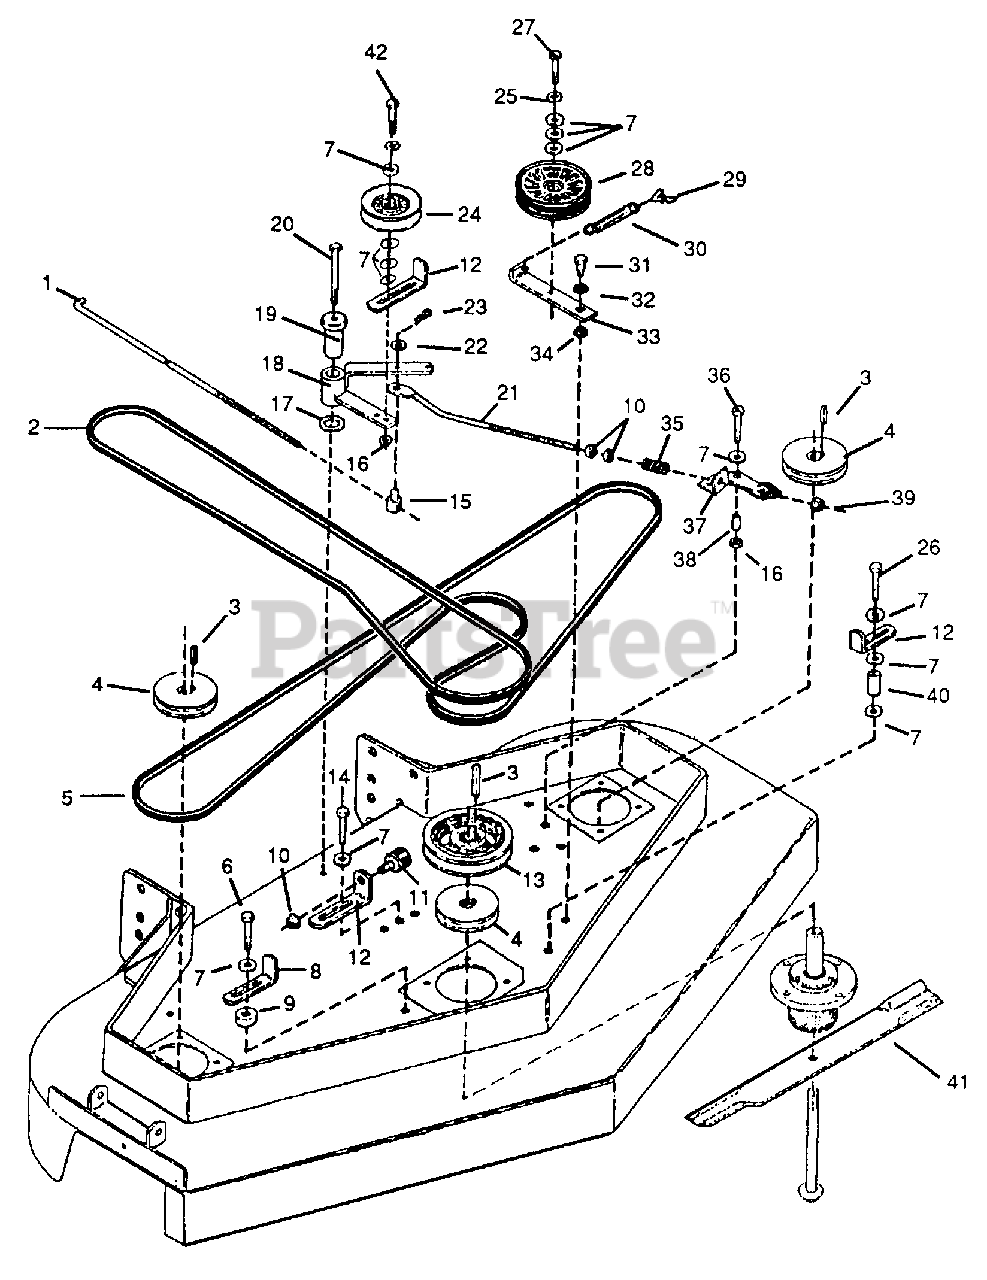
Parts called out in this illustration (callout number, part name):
1	Rod, Blade Engagement
2	Belt, Engine - Blade, 48"
4	Pulley
5	Belt, Blade- Blade, 48"
6	3/8"-16 x 1-1/4' Hex. Hd. Cap Screw
7	3/8" Flat Washer
8	Belt guide
9	Spacer
10	5/16"-18 Flange Nut
11	Bumper, Blade Control Lever
12	Beltguide
13	Pulley
14	3/8" -16 x 1' Hex. Hd. Cap Screw
15	Swivel
16	3/8' Flange Nut
17	1" Machinery Bushing
18	Idler Arm
19	Pivot Bushing
20	3/8' -16 x 3' Hex. Hd. Cap Screw
21	Rod, Blade Brake
22	5/16- Flat Washer
23	#13 Hair Pin Cotter
24	Pulley
25	3/8' Spring Lock Washer
26	3/8 -16 x 2-1/4' Hex. Hd. Cap Screw
27	3/8' -16 x 1-1/2' Hex. Hd. Cap Screw
28	Idler Pulley W/Bushing
30	Spring
31	Shoulder Bolt
32	Bellville Washer
33	Idler Arm
34	Snap Bushing
35	Spring
36	3/8"-16 x 2" Hex. Hd. Cap Screw
37	Braco Arm Assembly
38	Spacer
39	5/16" Flex Lock Nut
40	Spacer
41	16-1/2" Blade, High Lift
42	3/8' - 16 X 2' Hex. Hd. Cap Screw
